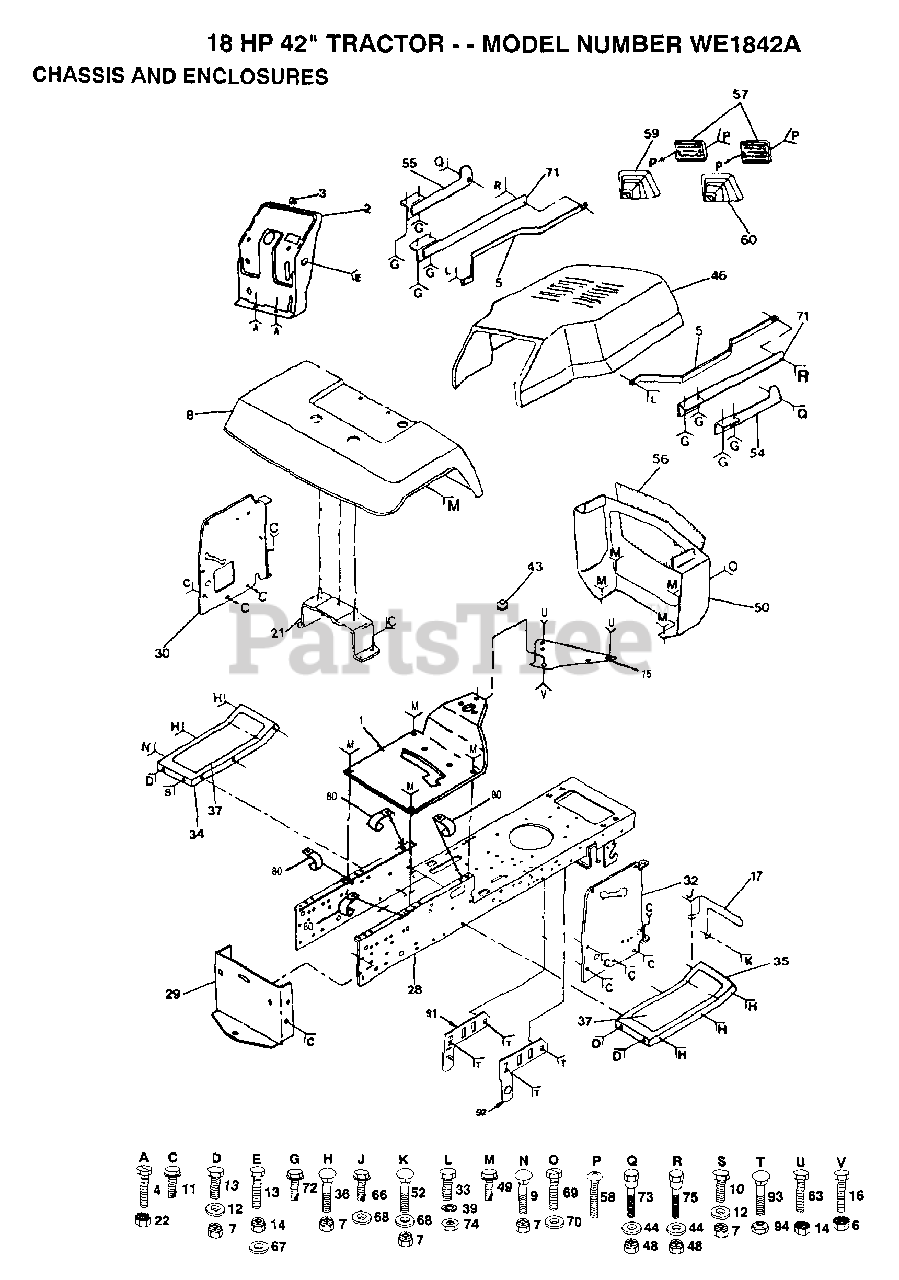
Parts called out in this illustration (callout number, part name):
1	SADDLE. 6SP
2	DASH.ASM.H/STP
3	PLUG-DASH T
4	SCREW
11	SCREW
12	WASHER
16	BOLT
17	MUFFLER GUARD
21	BRKT FENDER
30	DASH PANEL LH
33	BOLT LT
36	BOLT
37	"PAD,FOOTREST"
39	LOCKWASHER
48	NUT CROWNLOCK
49	SCREW LT
52	BOLT D
54	STRAP ASSY T
55	STRAP ASSY T
66	SCREW GTV
68	WASHER HYT
69	SCREW
71	STRAP ASSY-REAR T
73	BOLT T
75	"BOLT,SHOULDER"
80	"CLIP,INSULATOR"
91	PIVOT BRKT LH
92	PIVOT BRKT RH
94	NUT
